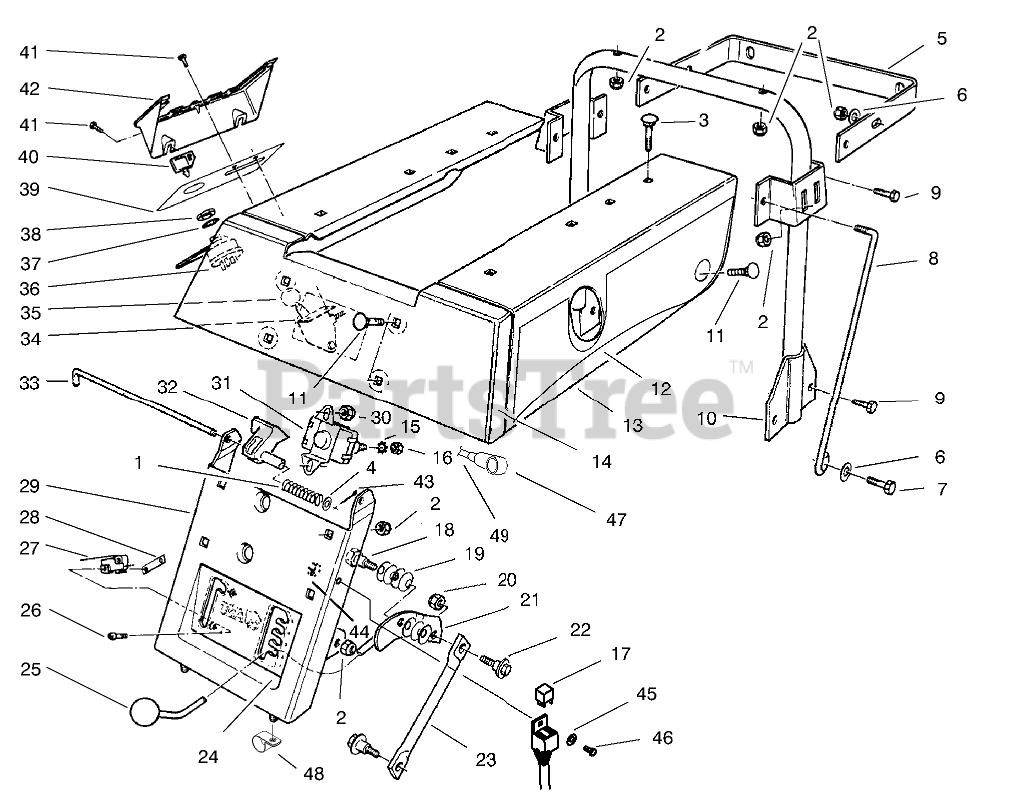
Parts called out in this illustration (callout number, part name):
1	SPRING-COMPRESSION
2	NUT-LOCK, NI
3	SCREW-CARR
4	WASHER-FLAT
5	STANDBAR
6	WASHER-PLAIN
7	SCREW-HH
8	BRACE-SEAT SUPPORT
9	SCREW-HH
10	SEAT SUPT WA (BLACK)
11	BOLT-CARR
12	DECAL - RH SIDE PANEL
13	SEAT BODY WA (RED)
14	DECAL - W.H. INSIGNA
15	WASHER-LOCK
16	NUT-JAM
17	RELAY
18	BOLT-SHOULDER
19	WASHER-BELLEVILLE
20	NUT-LOCK, NI
21	HOC HDLE WA
22	BOLT-SHOULDER
23	LINK-HOC
24	DECAL - HOC/DECK ENGAGE
25	KNOB-CONTROL
26	SCREW-SPH
27	SWITCH-MICRO
28	NUT-SPEED
29	FRT SEAT SUP WA RED
30	NUT-LOCK, NI
31	SOLENOID
32	PROP-SEAT
33	ROD-SEAT BASE
34	CONTROL-THROTTLE
35	KNOB-CONTROL
36	Switch-Ignition (Incl. Ref. #37 & 38)
37	WASHER-TOOTH, INTERNAL
38	NUT-HH
39	DECAL - CONTROL PANEL
40	KEY-IGNITION
41	SCREW-THD FORM, HWH
42	COVER-CONTROL PLATE
43	PIN-COTTER
44	NUT-LOCK, NI
45	WASHER-FLAT
47	BOOT-INSULATOR, TERMINAL
48	CLIP-FUEL LINE
49	ASM - CABLE
